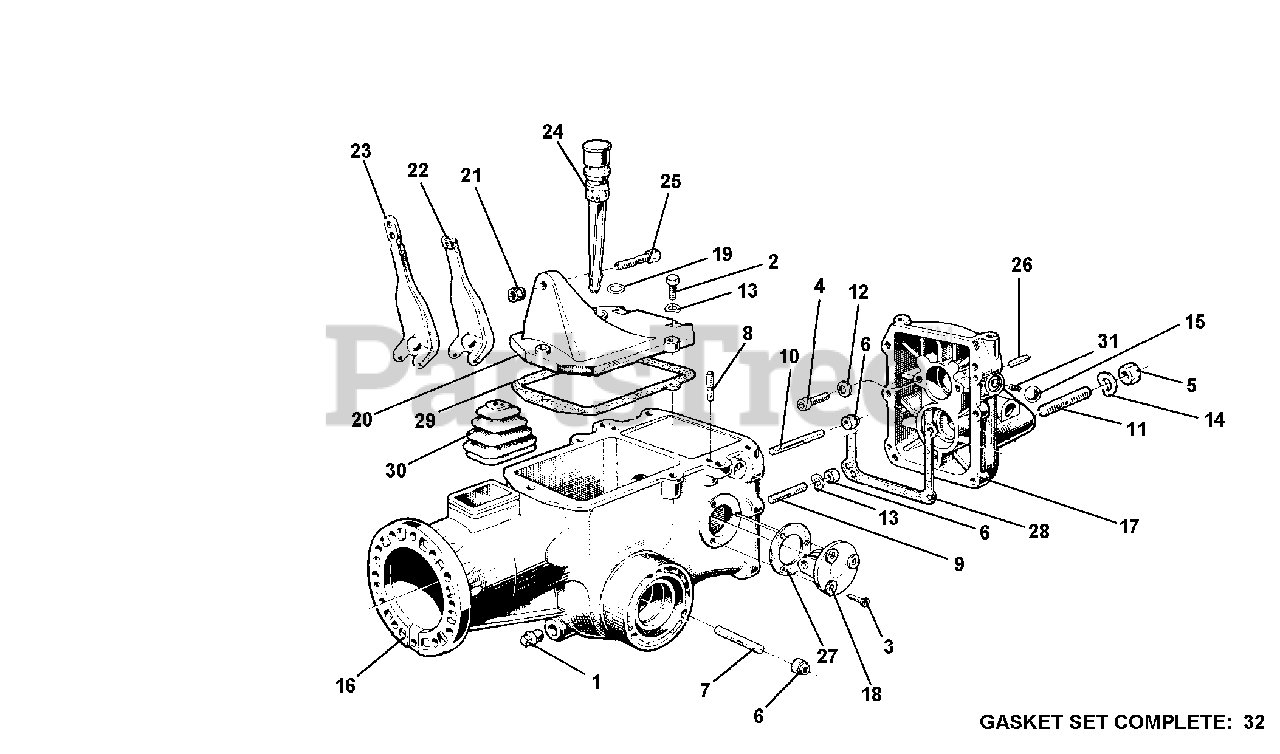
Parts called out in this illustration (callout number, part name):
1	PLUG 1/4 GAS
2	SCREW TE M8 X 25
3	SCREW M6 X 16
4	SCREW TCCEI M8 X 12
5	NUT M12 X 1.25 UNI 5587 6S
6	NUT, SELF LOCKING M8
7	STUD M8 X 46 X 20 X 12
8	STUD M8 X 38 X 14 X 20
9	STUD M8 X 46 X 16 X 16
10	STUD M8 X 58 X 16 X 16
11	ST.56M12X1.25X26XM12X22 8G
12	SUPER WASHER 8 DIN 6796
13	WASHER, LOCK 8.4
14	WASHER, LOCK 13
15	BALL 15/32 RIV RB-11.906
16	HOUSING BODY
17	HOUSING COVER
18	FLANGE, REVERSE SPEED
19	RUBBER RING
21	STOP RING NUT
22	CLUTCH LEVER
23	CLUTCH LEVER
24	CAP, WITH MEASURING ROD
25	SCREW, ADJUSTING M8
26	PARALLEL PIN D 6 X 20
28	GASKET COVER
29	GASKET COVER
31	P.T.O. SPRING
32	GASKET SET COMPLETE 715-725
